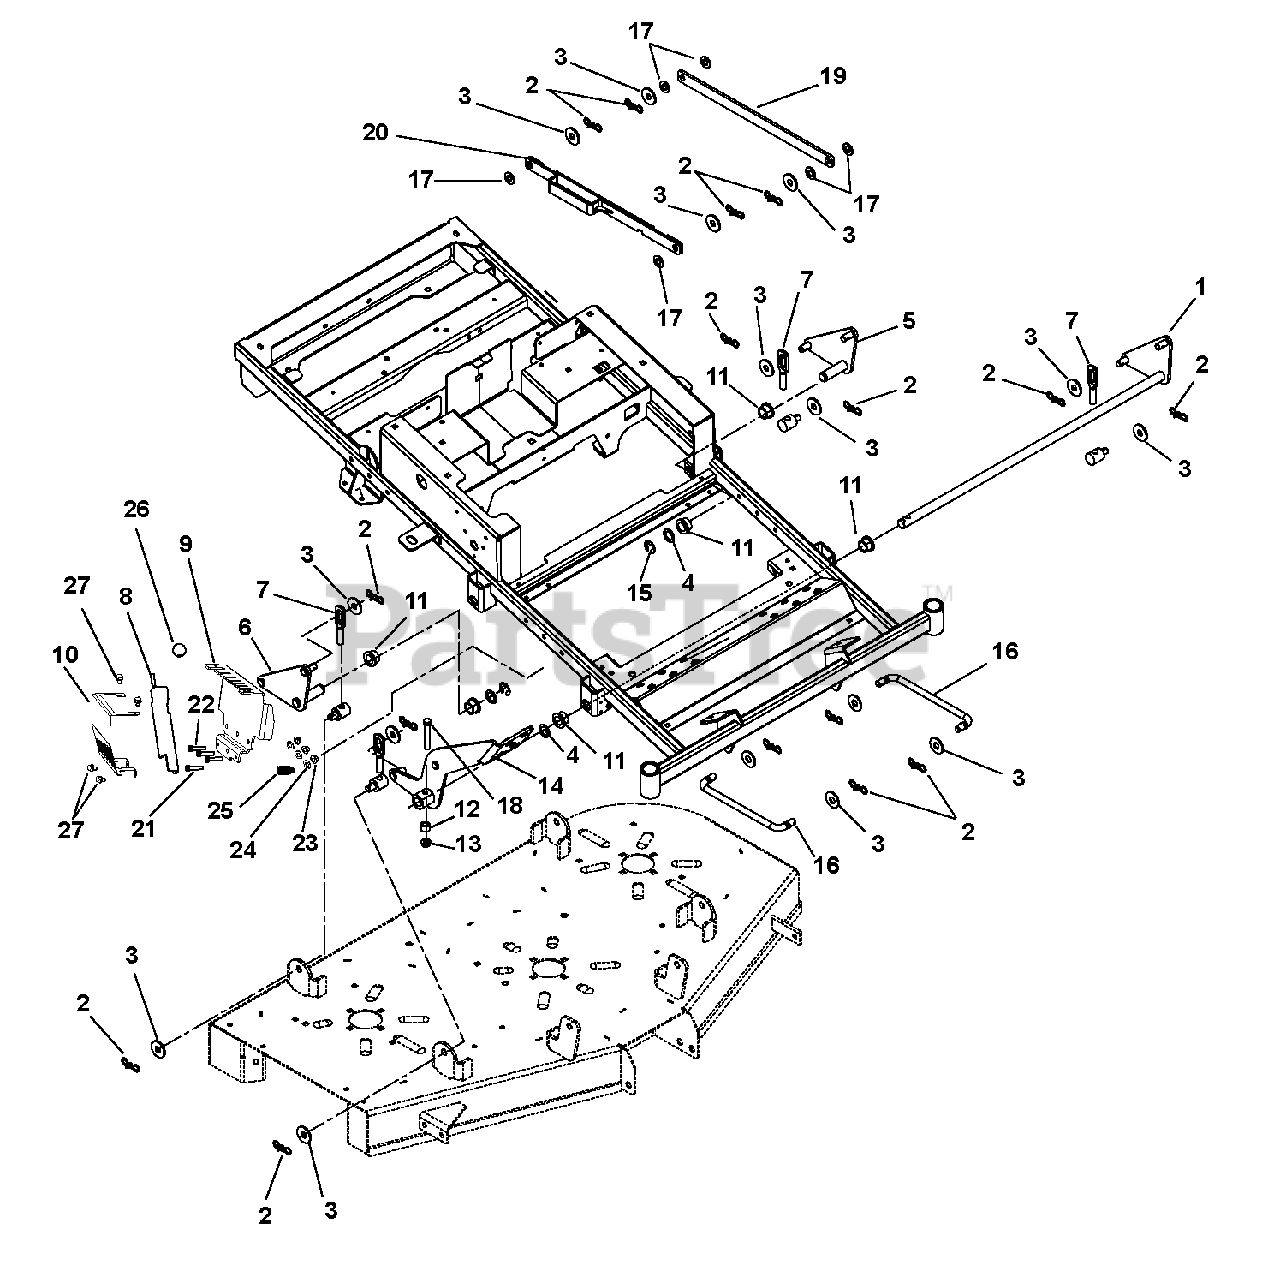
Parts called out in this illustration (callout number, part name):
1	Weldment, Deck Pivot
2	Pin, Bow Tie Locking Cotter .091 x 1.875
3	Washer, Flat Steel.511 x 1.441 x .125
4	Washer, Flat Steel .754 x 1.125 x .062
5	Weldment, Deck Pivot ZTXL Rear Left Hand
6	Weldment, Deck Pivot ZTXL Rear Right Hand
7	Assembly, Deck Link
8	Lever, Weldment
9	Bracket, HOC XL
10	Guard, Plate Styled HOC
11	Bushing, Flange .750 x 1.000 x .625 x 1.250
12	Bushing, Sleeve .391 x .688 x .52
13	Nut, Flange Nyloc 3/8-16
14	Weldment, ZTXL Foot Pedal
15	Ring, Retaining-External .750 x .050
16	Link, Drag
17	Washer, Flat Nylon .52 x 1.00 x .08
18	Bolt, Hex .38-16 x 2.50 Grade 5
19	Link, Lift
20	HOC, Link Retaining XL
21	Bolt, Hex .38-16 x 2.25
22	Bolt, Hex .38-16 x 1.75 Grade 5
23	Nut .38-16 Nyloc Flange
24	Washer, Flat Steel .38 x .875 x .083
27	Screw, Tapping Hex Washer Head Thread Rolling .25-20 x .50 YWZ
